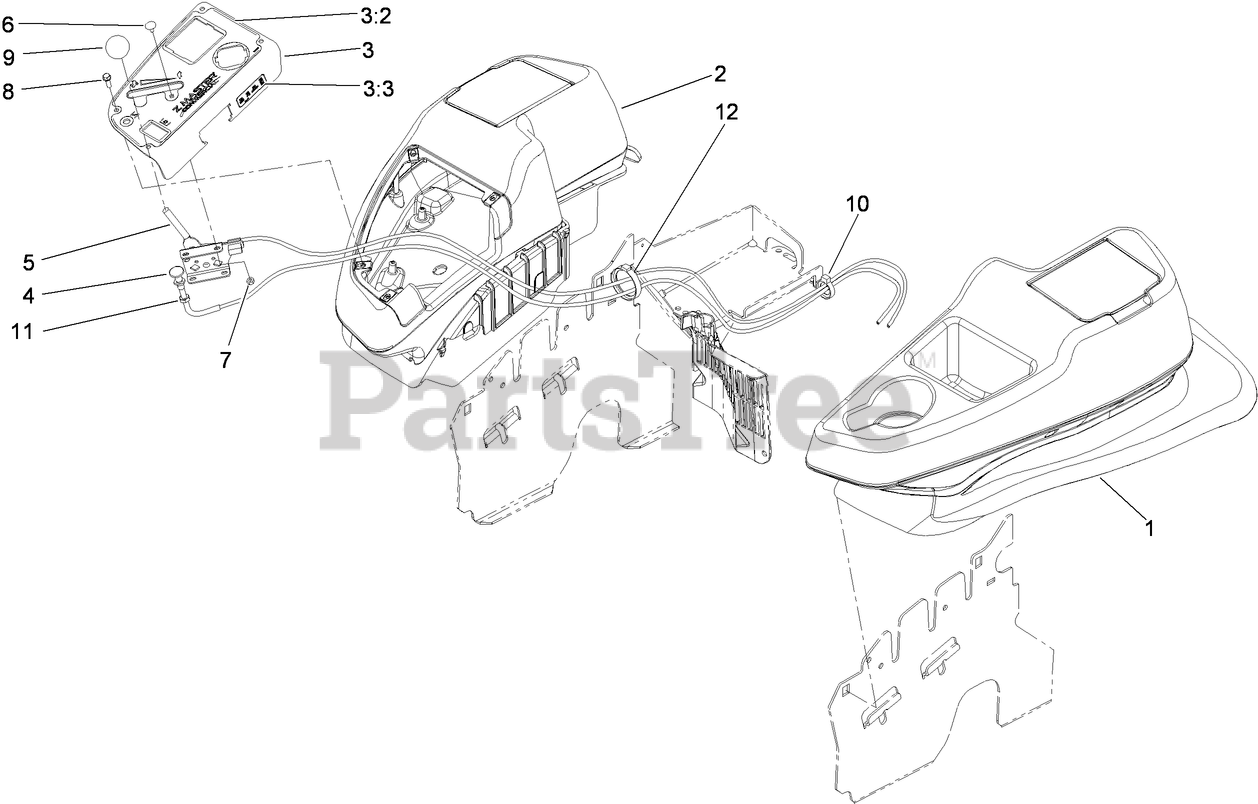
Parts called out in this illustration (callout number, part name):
1	LH CONSOLE ASM
2	RH CONSOLE ASM
3	CONTROL PANEL ASM
3:2	DECAL-PANEL, CONTROL
3:3	DECAL-FUSES
4	CONTROL-CHOKE
5	THROTTLE CONTROL ASM
6	BOLT-CARR
7	NUT-LOCK, NI
8	SCREW-HWH
9	KNOB-BALL
10	CLAMP-HOSE
11	NUT-HJ
12	CLAMP-HARNESS
